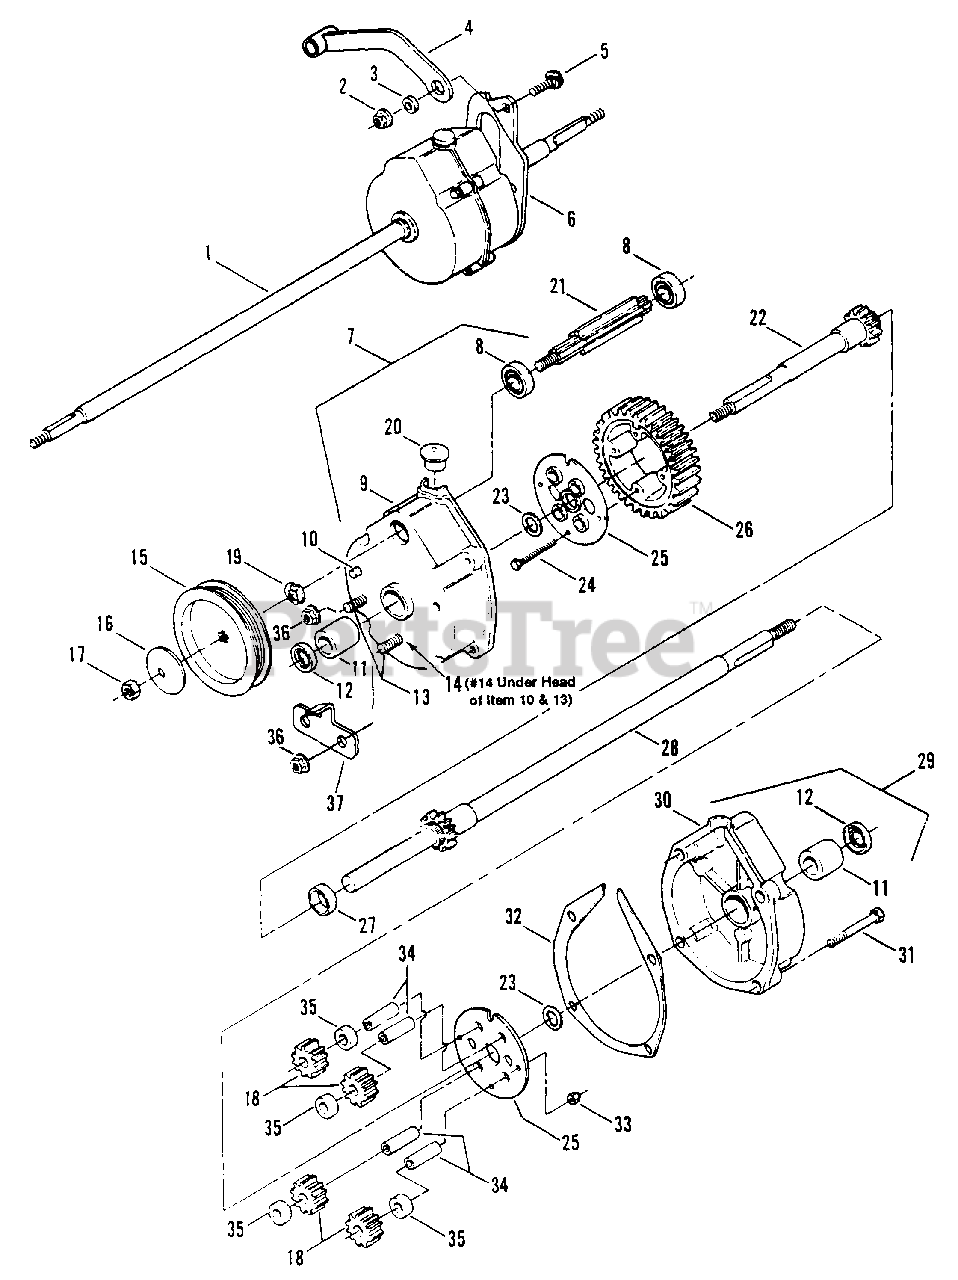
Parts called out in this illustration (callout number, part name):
1	ASSEMBLY, Transmission
2	NUT, 5/16-18 Hex Flange Lock
3	SPACER
4	WELDMENT, Drive Pivot
5	BOLT, 5/16-18 x 5/8" Flat Head Carriage
6	BRACKET, Differential
7	ASSEMBLY, Housing, Right Side
8	BEARING, Ball
9	HOUSING, Right Side
10	STUD, 5/16 Rib Neck
11	BEARING, Differential
12	SEAL, 5/8 I.D.
13	SCREW, 5/16-24 x 1-1/8" Rib Neck
14	GASKET, 5/8 O.D.
15	PULLEY, Poly-V Belt
16	WASHER, Spring
17	NUT, 5/16-24 Hex Lock
18	GEAR, Pinion (12 Teeth)
19	WASHER, Spring
20	PLUG, Housing
21	ASSEMBLY, Input Gear
22	AXLE, Short
23	WASHER, Thrust
24	SCREW, #10-32 x 1 1/2" Hex Head Cap
25	PLATE
26	GEAR, Differential (46 Teeth)
27	SPACER, Axle Gear
28	AXLE, Long
29	ASSEMBLY, Housing, Left Side
30	HOUSING, Left Side
31	SCREW, 1/4-20 x 1 1/4" Self-Tapping
32	GASKET, Housing
33	NUT, #10-32 Hex Lock
34	SHAFT, Pinion
35	SPACER, Pinion Gear
36	NUT, 5/16-18 Hex Flange Lock
37	GUIDE, Rear
